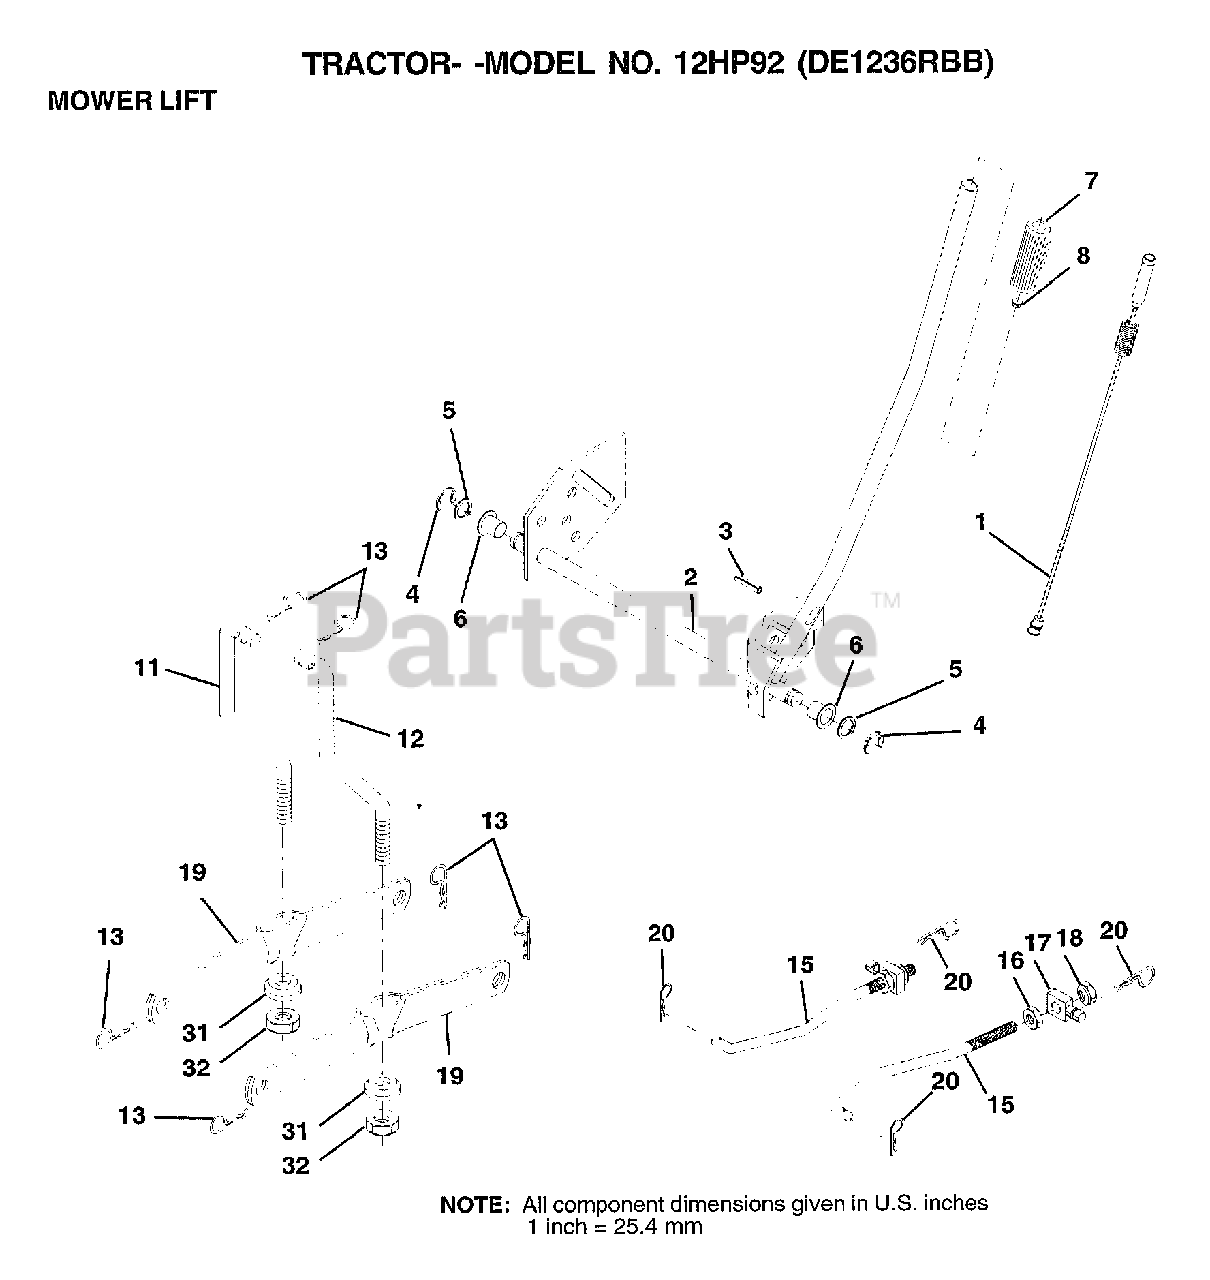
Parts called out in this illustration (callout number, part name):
1	WIRE ASM W.SPRING
2	"SHAFT ASM LIFT,RH"
3	PIN-GROOVE LT
5	WASHER
6	NYLON BEARING
7	GRIP
11	LINK.LIFT.LH.CRD
12	LINK.LIFT.RH.CRD
15	LINK, FRONT
16	NUT
17	TRUNION
18	NUT.LK.W/WSH.1/2.
19	ARM SUSP REAR
20	RETAINER SPRING
31	BEARING PVT LH
32	NUT.CROWNLOCK.3/8
